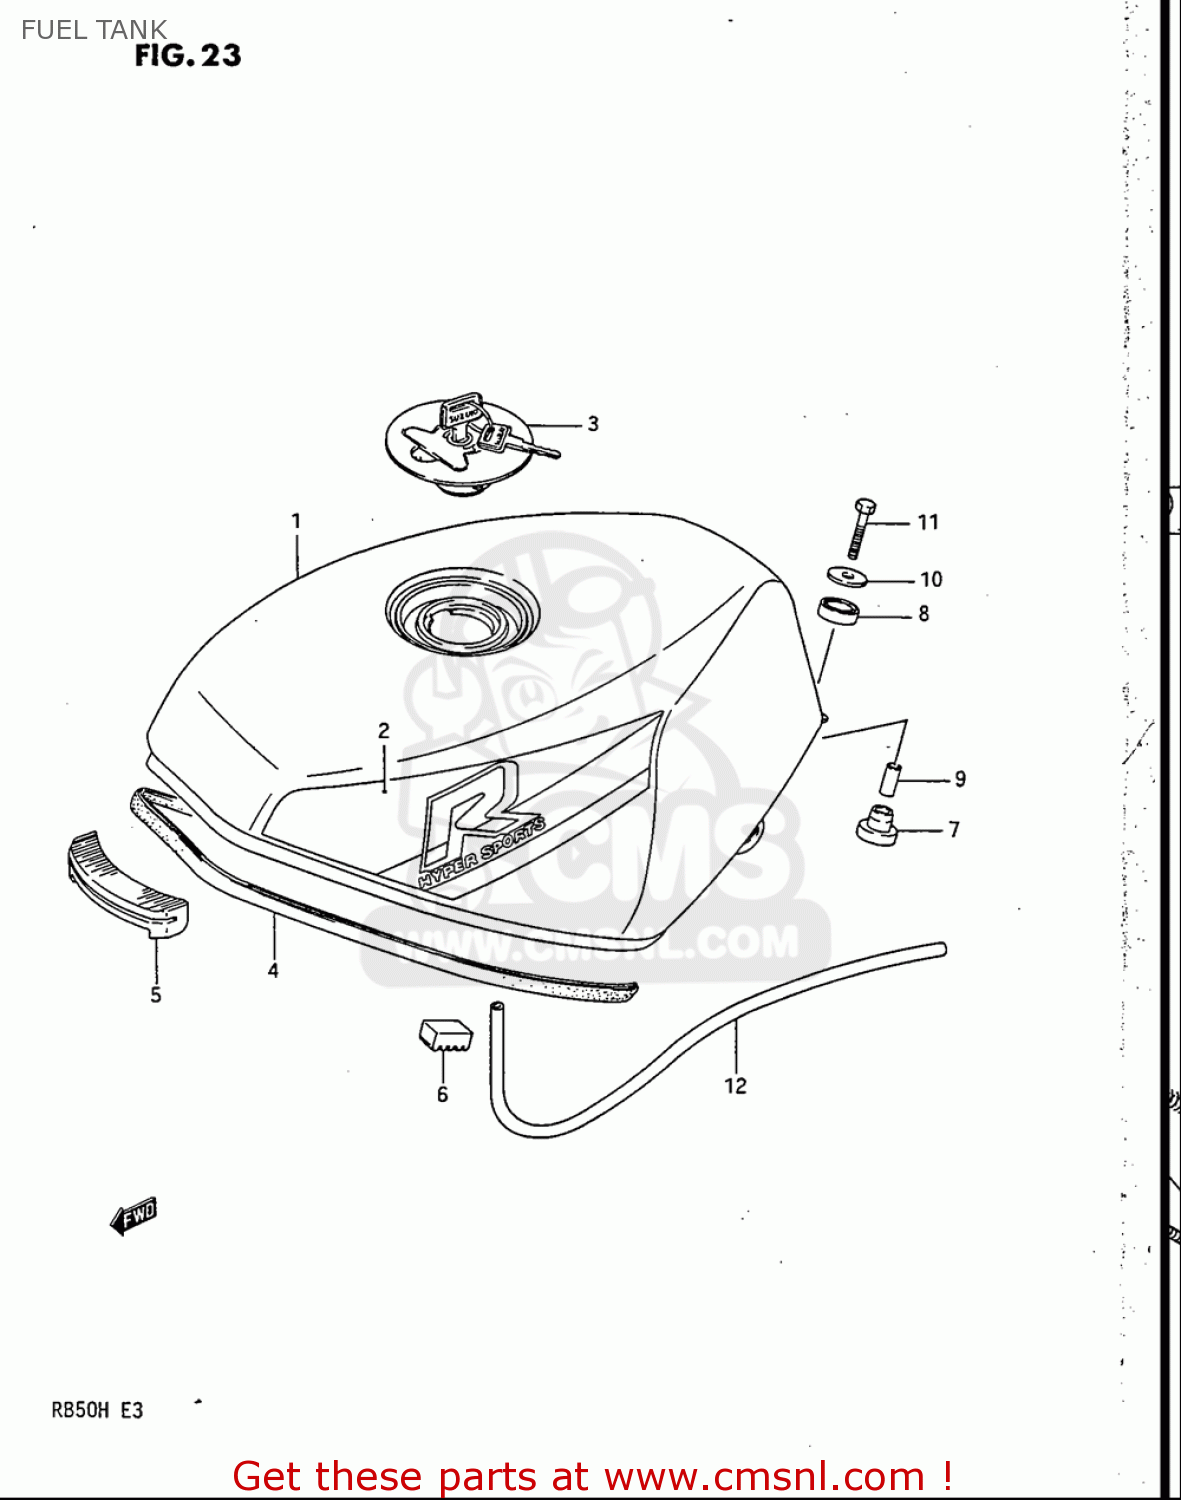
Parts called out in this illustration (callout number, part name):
3	CAP SET,FUEL TANK
4	MOLDING
7	CUSHION
8	CUSHION
9	SPACER(6.5X9X19)
10	WASHER(6.5X24X1.6)
11	BOLT
12	HOSE(5X8.2X2000)
